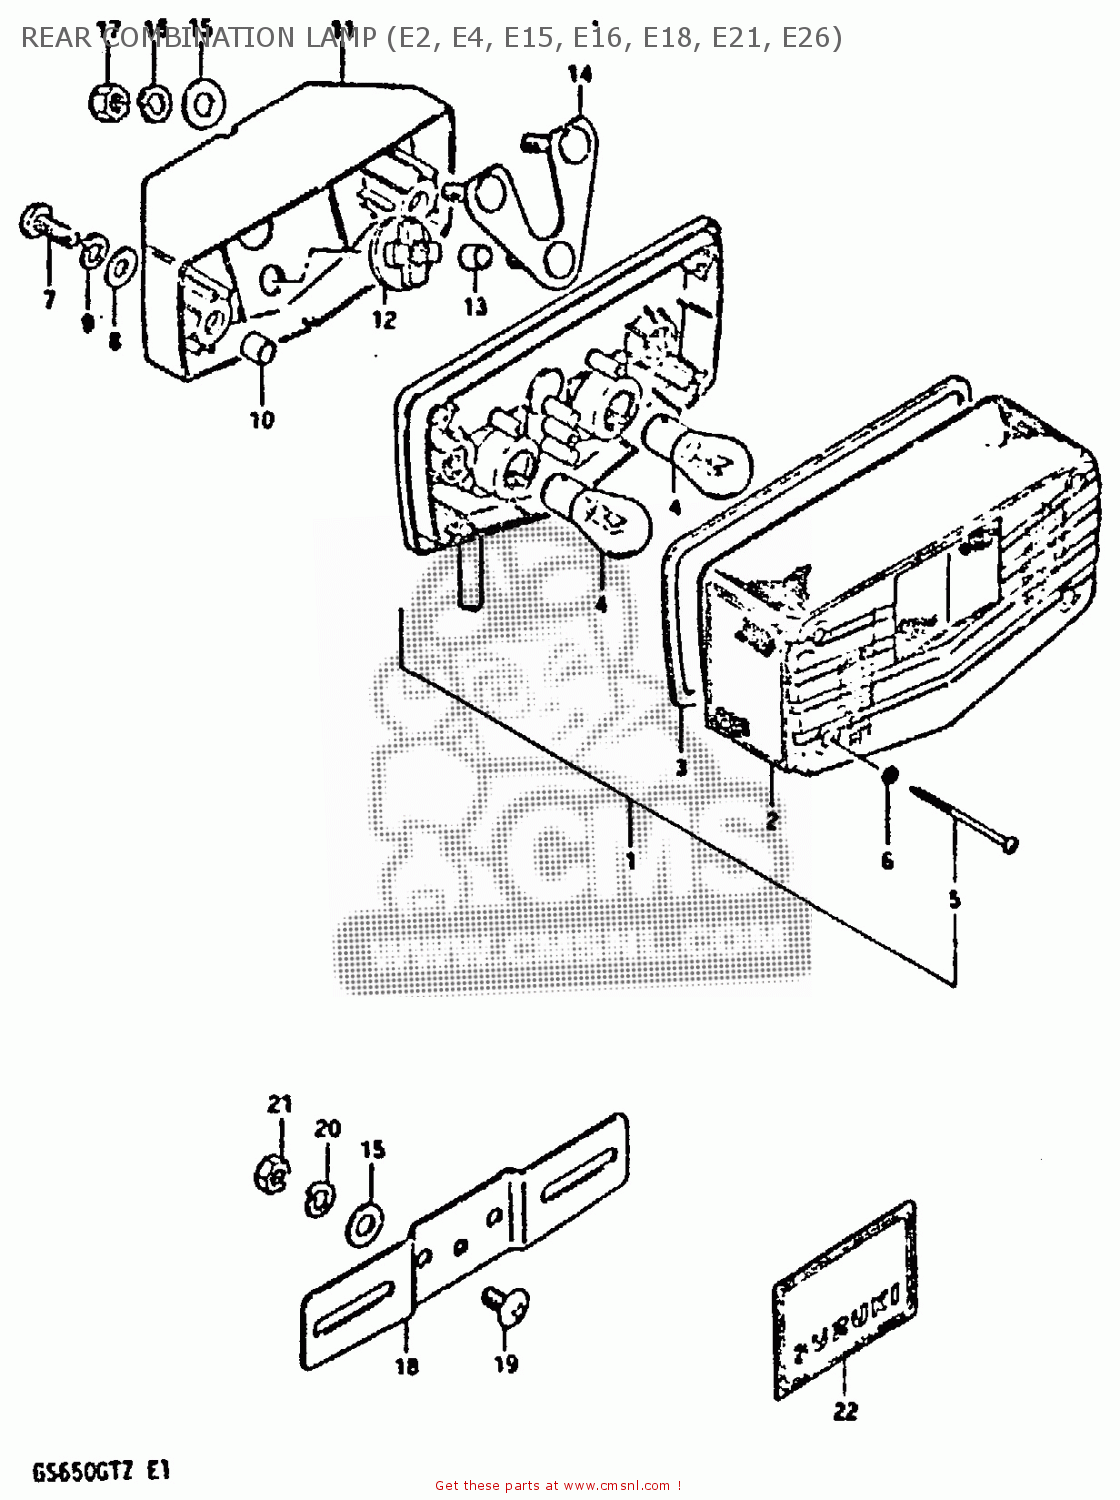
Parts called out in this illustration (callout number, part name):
1	LAMP UNIT, TAIL
2	LENS
3	GASKET,REAR COMBINATION LAMP LENS (NAS)
4	BULB 12V21/5W
5	SCREW
6	GASKET (NAS)
7	SCREW
8	WASHER
9	LOCK WASHER
10	SPACER,REAR COMBINATION LAMP
11	BRACKET UNIT,TAIL LAMP
12	CUSHION,REAR COMBINATION LAMP
13	SPACER,REAR COMBINATION LAMP
14	PLATE,REAR COMBINATION LAMP
15	WASHER
16	LOCK WASHER
17	NUT
18	PLATE,RR LICENSE
19	SCREW
20	LOCK WASHER
21	NUT
